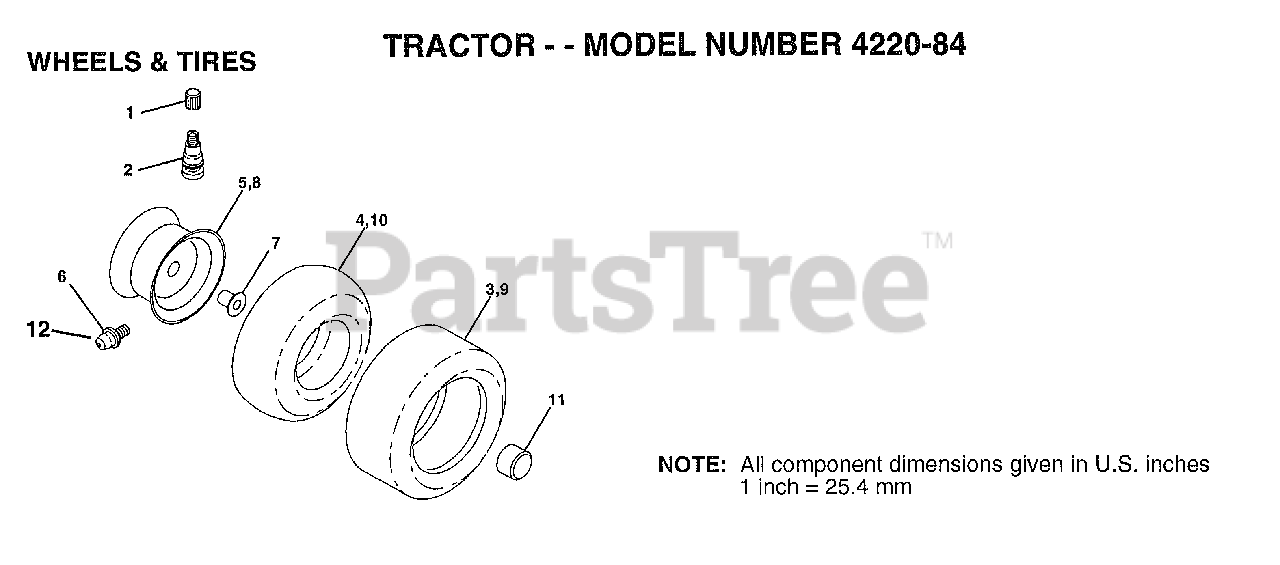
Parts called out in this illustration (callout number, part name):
1	VALVE CAP
2	VALVE STEM LT
4	TUBE.16X6.5/7.5-8
5	RIM.FRONT.
6	FITTING LT
7	"FLANGE, BEARING"
8	"WHEEL,REAR"
10	TUBE.23X8/10-12
11	HUB CAP
12	ZERK FITTING M
